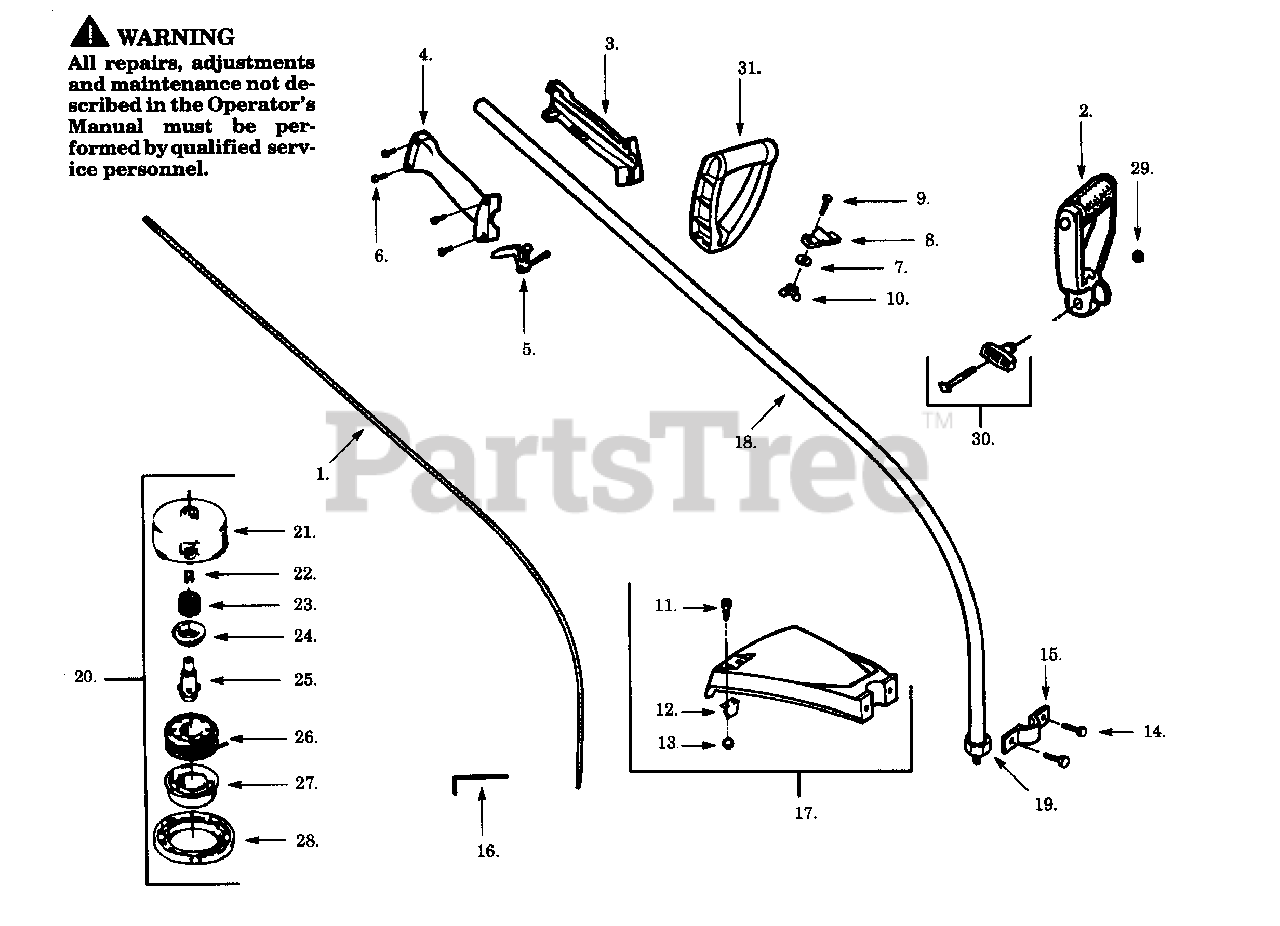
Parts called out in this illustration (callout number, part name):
1	Drive Shaft
3	Throttle Hsg. (Left)
4	Throttle Hsg. (Right)
5	Throttle Lever
12	Line Limiter
13	Locknut
15	Bracket Shield
16	Hex Wrench (5/32)
17	Shield Kit Ass'y.
18	Drive Shaft Hsg.
19	Dust Cup
20	Cutting Head Ass'y.
21	Hub Ass'y.
22	Line Saver
24	Spring Cap
25	Drive Gear
26	Spool w/Line
27	Release Button
30	"T" Handle Ass'y.
31	Handle
